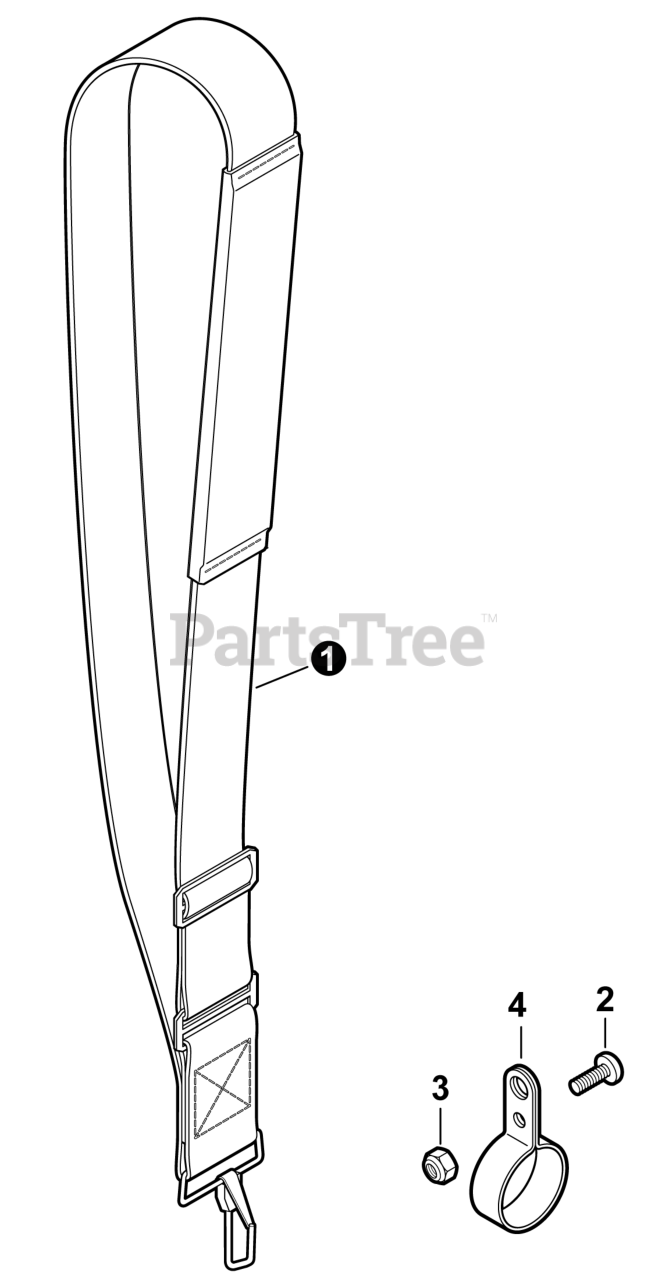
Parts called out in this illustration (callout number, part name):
1	STRAP ASSY, SHOULDER
2	BOLT, TORX 5x10
3	NUT, LOCK M5
